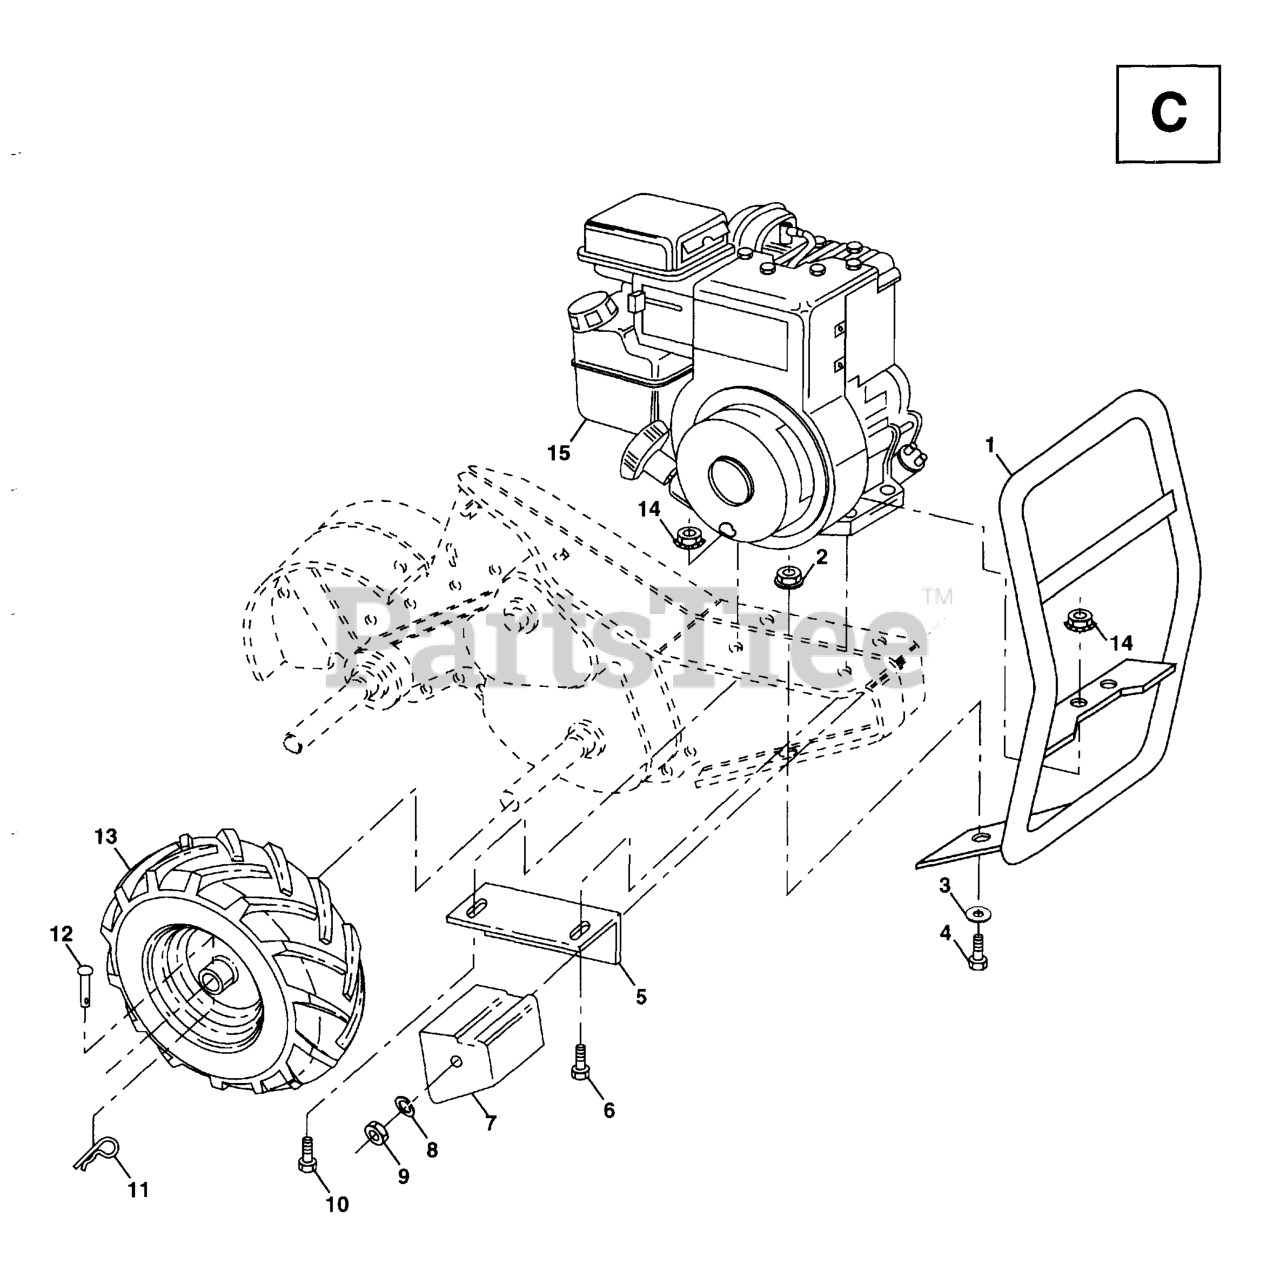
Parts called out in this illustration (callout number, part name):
1	BUMPER
2	LOCKNUT-FLANGE 5/16-18
3	WASHER
4	BOLT
5	DNO BRACKET RH CRT
6	Bolt Fin Hex 5/16 - 18 Unc x 2 Gr. 2
7	COUNTERWEIGHT, RH
8	WASHER, LOCK 3/8
9	NUT.HEX.3/8-16UNC
10	BOLT
11	RETAINER M
12	RIVET,DRILLED
13	TIRE.16X4-8.CHEVRON.TILLER
14	NUT
